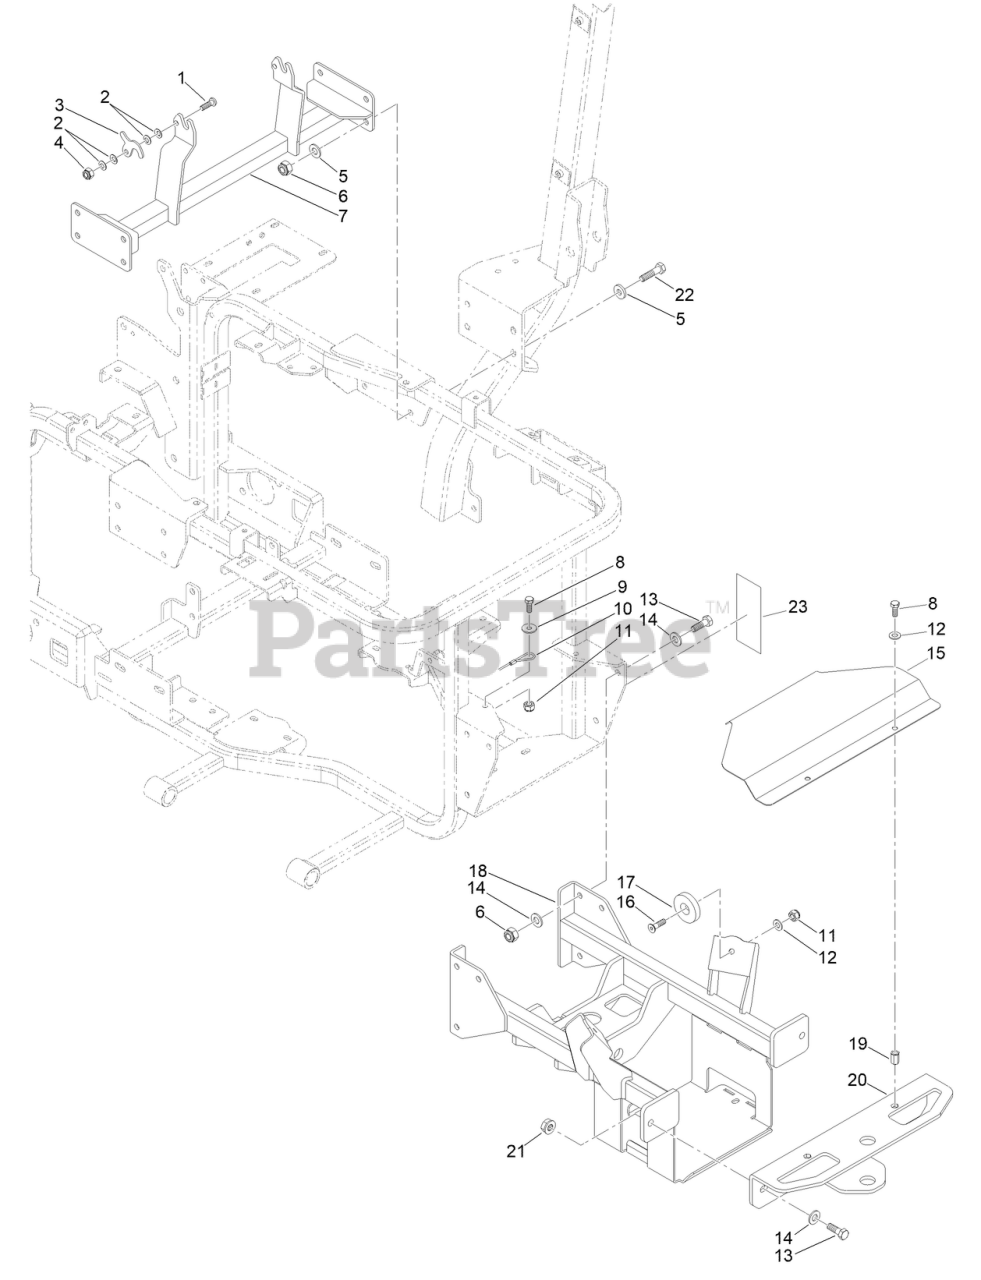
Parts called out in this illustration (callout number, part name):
2	WASHER, BELLEVILLE
3	HOOK, CHUTE
5	WASHER
7	CHASSIS, CENTRAL BAR
9	WASHER
10	CABLE, RADIATOR
12	WASHER
14	WASHER
15	COVER, BATTERY
17	SUPPORT
18	CHASSIS, REAR AXLE
19	INSERT-HEX
20	BUMPER
23	DECAL-MODEL/SERIAL
